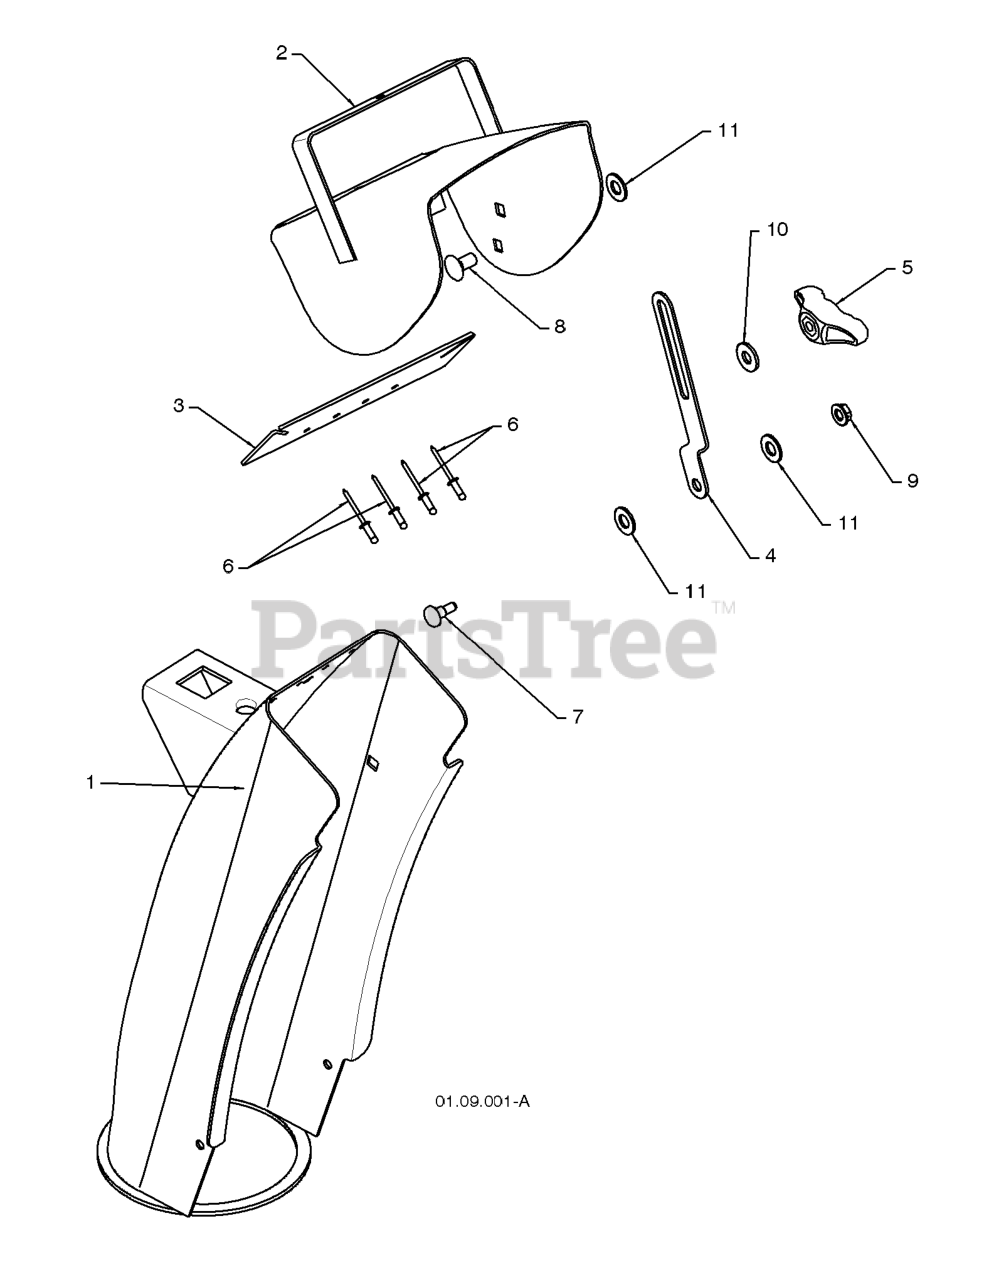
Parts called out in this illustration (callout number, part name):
1	CHUTE ASSEMBLY
2	DEFLECTOR.WELDMENT.PNT.ORANGE
3	SEAL.DEFLECTOR
4	STRAP, CHUTE
5	KNOB, DEFLECTOR
6	RIVET BLIND
7	SHOULDER BOLT
8	BOLT
9	NUT.HEX.FLANGE.1/4
10	WASHER.20X8.5
11	WASHER, NYLON FRICTION
